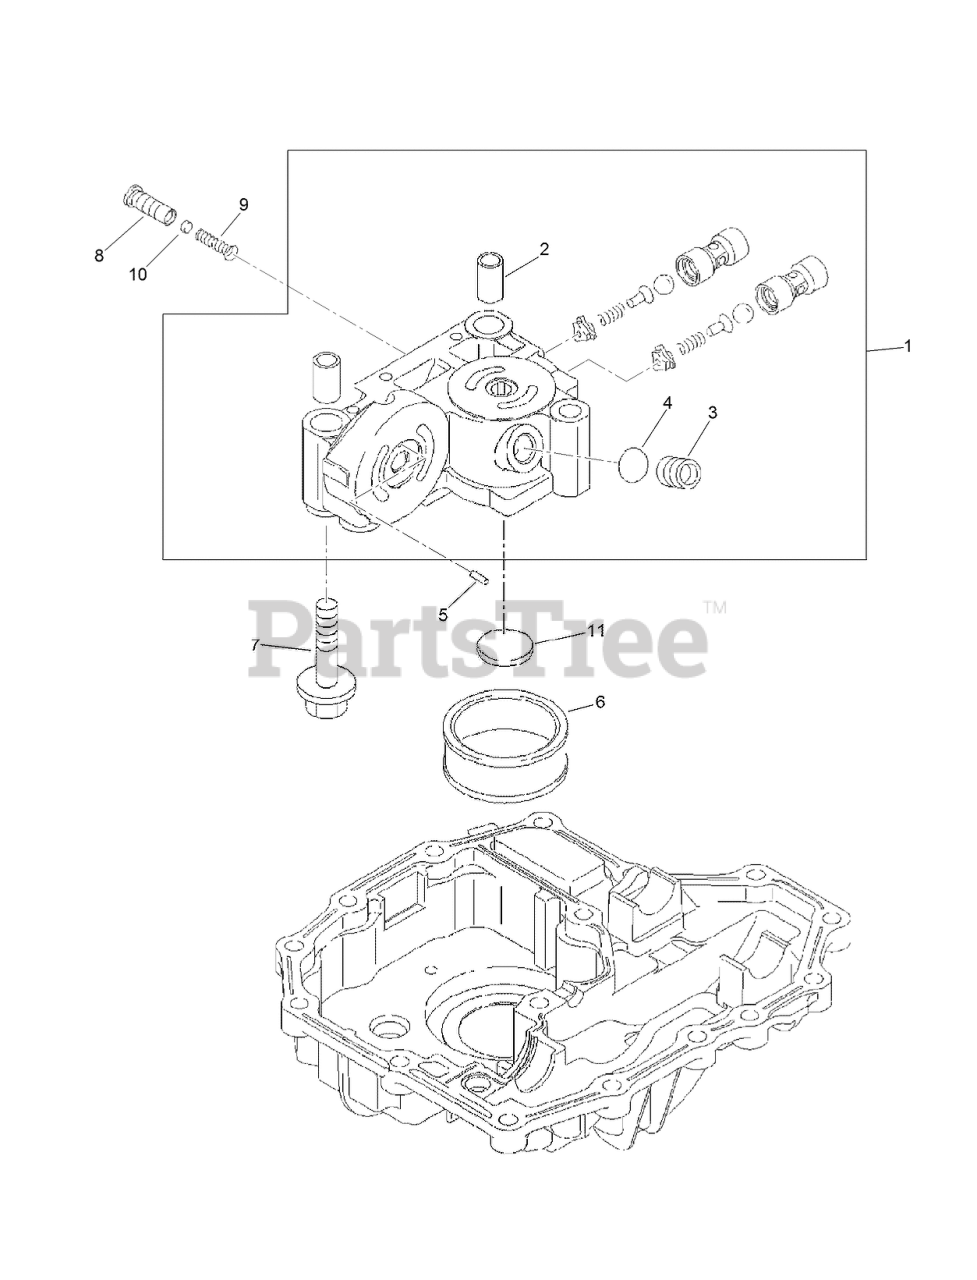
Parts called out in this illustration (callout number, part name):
1	Case-Center
2	Pin-Knock
4	PACKING
6	FILTER
9	Spring
10	Filter
11	Magnet
